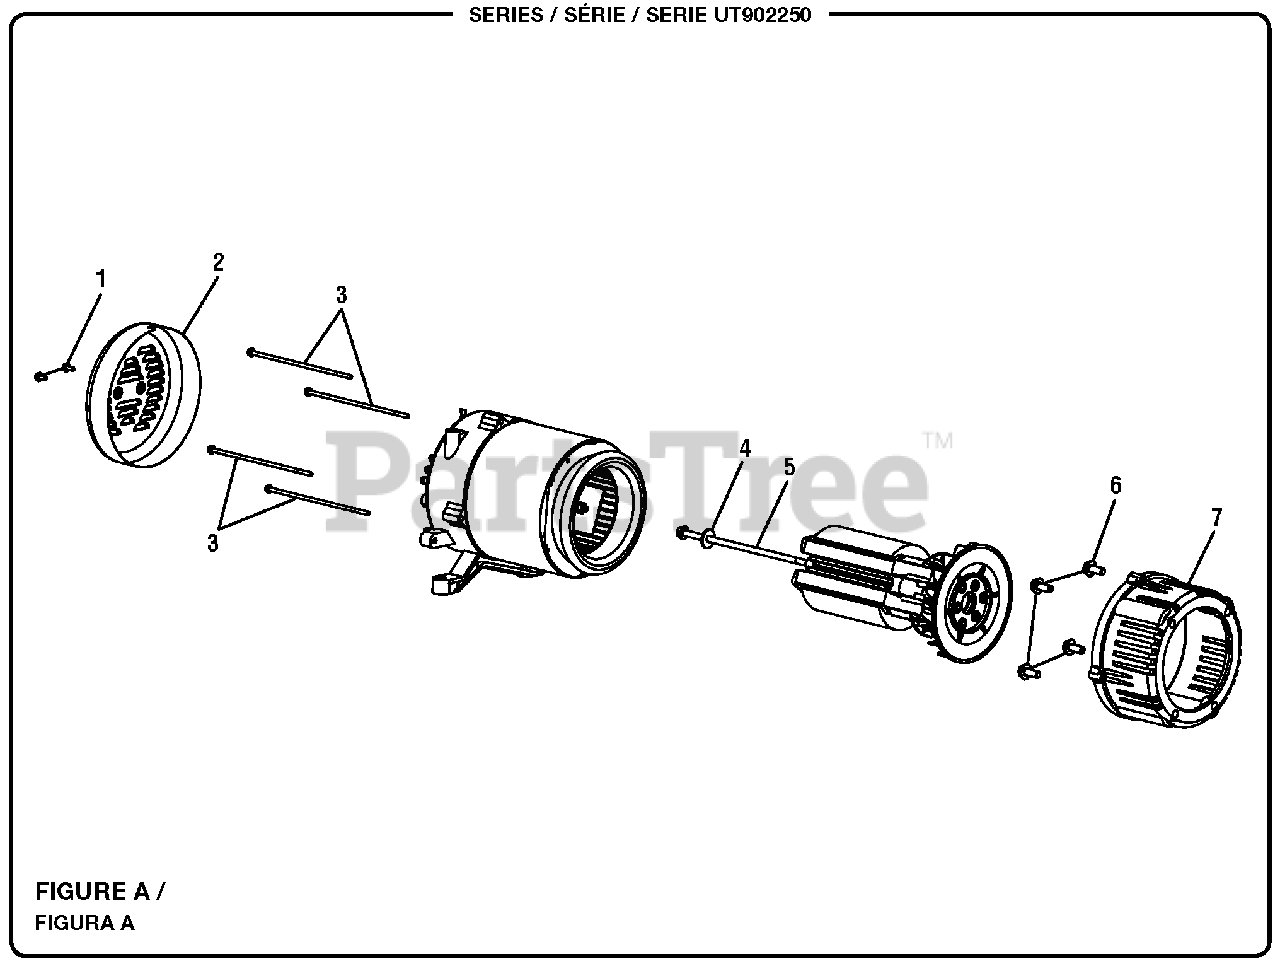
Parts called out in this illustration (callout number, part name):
1	Bolt (M5 x 10 mm, Flange Hex Hd.)
2	Brush Cover
3	Bolt (1/4-20 x 6 in., Hex. Hd.)
4	Lock Washer (5/16 in.)
5	Bolt (5/16-24 x 6-5/8 in., Hex. Hd.)
6	Bolt (3/8-16 x 1-1/4 in.)
7	Engine Adapter
